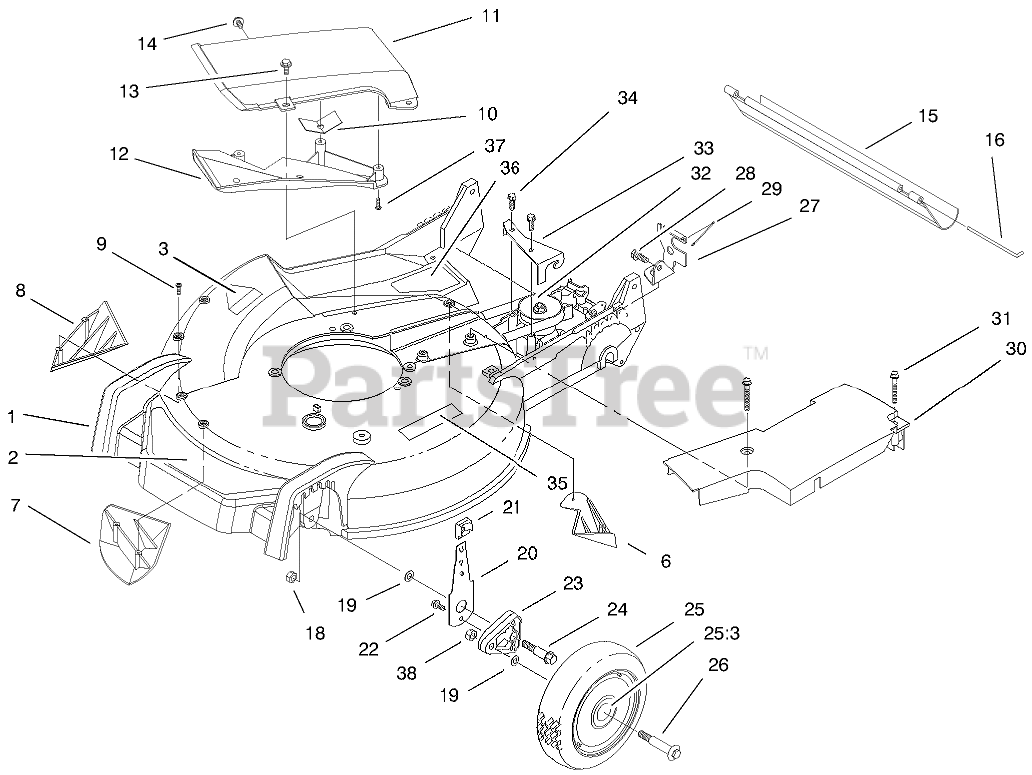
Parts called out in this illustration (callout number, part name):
1	HOUSING
2	DECAL - DECK
3	DECAL-DANGER
6	KICKER-REAR
7	KICKER-FRONT
8	KICKER-RH
9	SCREW-PPH
10	Guard-Cover
11	COVER W/DEFLECTOR
12	Deflector-Recycler
13	SCREW-HWH
14	SCREW AND WASHER ASM
15	SHIELD-TRAILING
16	ROD-SHIELD
18	NUT-LOCK
19	WASHER
20	FRONT SPRING ARM ASM
21	KNOB-ARM
22	SCREW-HWH
23	ARM-PIVOT, FRONT
24	BOLT-SHOULDER
25	WHEEL ASM
25:3	BUSHING
26	BOLT-SHOULDER
27	Bracket-Adj. Trac
28	SCREW-HWHTF
29	RETAINER-CABLE
30	COVER-BELT
31	SCREW-HHFTF
32	GEARCASE ASM
33	Bracket-Guide
34	SCREW-HWHTF
35	DECAL-WARNING
36	DECAL - DANGER
37	Screw-PPH
38	NUT-JAM, LOCKING
